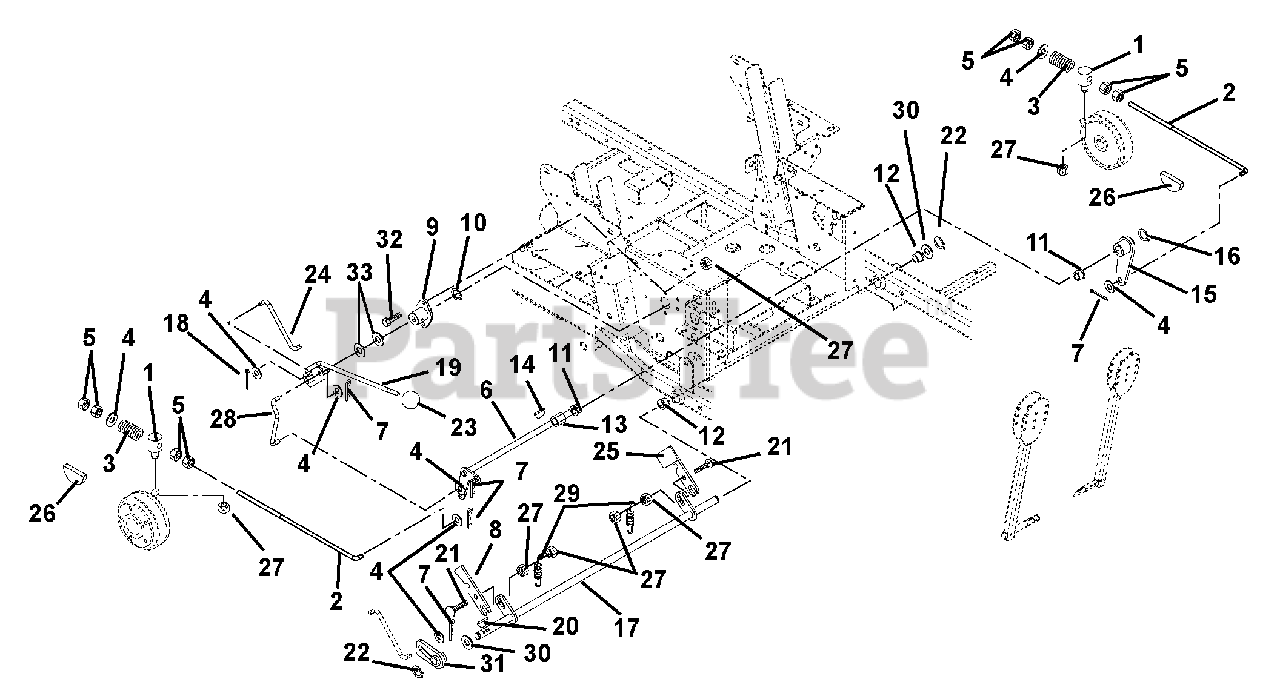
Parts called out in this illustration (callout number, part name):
1	Pivot, Brake Rod
2	Rod, Brake .38 x 19.00
3	Spring, Compression .143 x .71 x 2.00
3	Spring, Compression .142 x .710 x 1.75
4	Washer, Flat Steel .406 x .812 x .065
5	Nut, Hex .38-16
6	Shaft, Brake Cross
7	Pin, Hair
8	Slide, Interlocking Brake
9	Bushing, Flange
10	Ring, Retaining External .625 x .05
11	Bushing, Flange Nylon .762 x 1.00 x .58 x 1.48
12	Bushing, Flange .515 x .75 x .745 x 1.00
13	Bushing, Sleeve .75 x 1.00 x .75
14	Key, Woodruff .19 x .75 Hard #9
15	Arm, Brake Left Hand
16	Ring, Retaining External .625 x .050
17	Weldment, Mechanical Brake
18	Pin, Cotter External .09 x .75
19	Weldment, Brake Actuating
20	Key, Woodruff .13 x .63
21	Bolt, Round Head Square Neck .31-18 x 1.25 Grade 5
22	Ring, Retaining External .50 x .05
23	Knob, Steering Lock
24	Linkage, Brake Actuating
25	Interlock, Safety Switch
26	Pad, Disk Brake
27	Nut, Locking, Top Flange .31-18
28	Linkage, Brake Actuating
29	Spring, Tension .063 x .44 x 1.56
30	Washer, Flat Steel .505 x 1.00 x .062
31	Weldment, Parking Brake Hub
32	Bolt, Hex .31-18 x .75 Grade 5
33	Washer, Flat Steel .630 x 1.250 x .062
